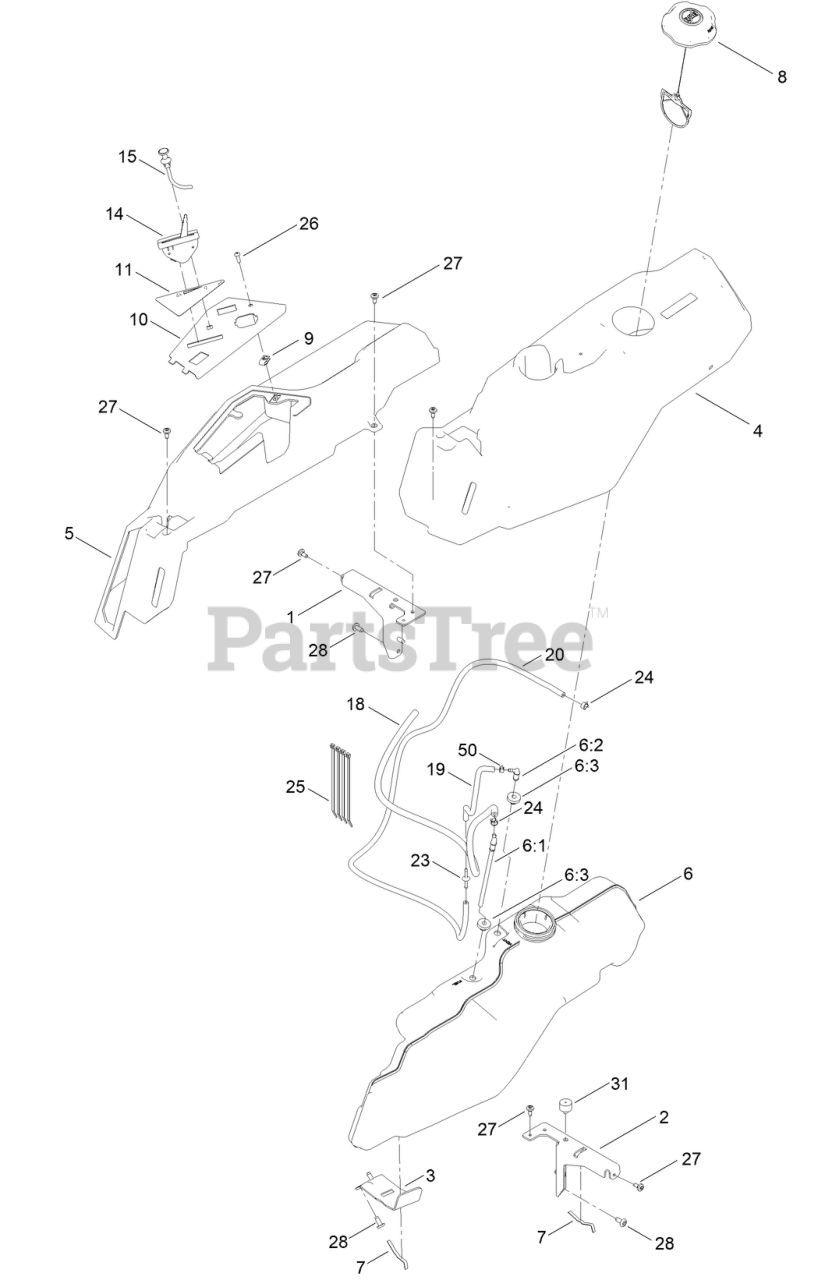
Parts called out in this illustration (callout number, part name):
1	SUPPORT-POD, RH
2	SUPPORT-POD, LH
3	SUPPORT-TANK, FUEL
4	POD-LH
5	POD-RH
6	TANK-FUEL ASM
6:1	CONNECTOR-ELBOW, 90 DEG
6:2	FITTING-ELBOW 90
6:3	BUSHING
7	SPRING
8	CAP-FUEL, RATCHETING
10	PANEL - CONTROL
11	DECAL-PANEL, CONTROL
14	CABLE-THROTTLE
15	CABLE-CHOKE
18	HOSE-FUEL
19	HOSE-FUEL
20	HOSE-FUEL
23	ADAPTER ORIFICE
24	CLAMP-HOSE
25	TIE-CABLE
26	SCREW-PRH
27	SCREW-SHOULDER
31	BUMPER-GROMMET
50	CLAMP-HOSE
